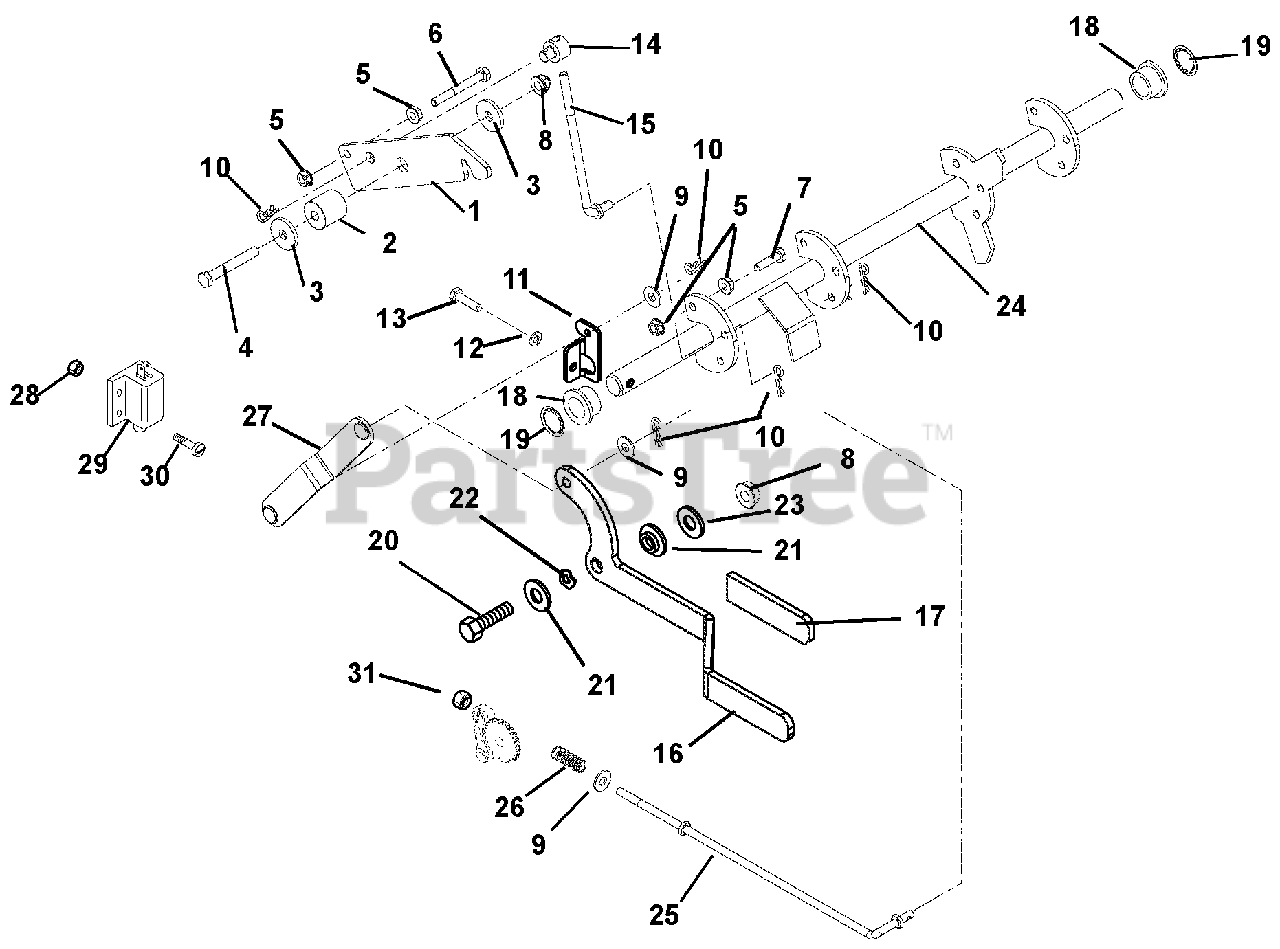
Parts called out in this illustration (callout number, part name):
1	LATCH, NEUTRAL
2	SPCR, FLG .32X.49X.192X1.00
3	WSHR-FL-STL .344X1.125X.135
4	@BLT-HEX .31-18X2.25 GR5 YWZC
5	@NUT-SPNLK-FLG .25-20 YWZC
6	@BLT-HEX .25-20X2.25 GR5 YWZC
7	@BLT-HEX .25-20X1.00 GR5 YWZC
8	@NUT-LK-NYL-FLG .31-18 YWZC
9	@WSHR-FL-STL.312X.734X.065 YWZ
10	PIN-HAIR INT .08X.18X1.18 YWZC
11	CRANK, PARKING BRAKE
12	@WSHR-LK .25X.062 REG YWZC
13	@BLT-HEX .25-20X1.00 GR5 YWZC
14	TRUNNION, BRAKE .31-18 UNC
15	BRAKE LINK
16	HANDLE, PARKING BRAKE
17	GRIP,HANDLE
18	BSHG-FLG .750X1.000X.625X1.250
19	NUT, PUSH -.75" SHAFT
20	@BLT-HEX .31-18X1.75 GR5 YWZC
21	BSHG-FLG .325X.501X.250X1.120
22	WSHR-WAVE .50X.75X.015 .13FRHT
23	WSHR-FL-STL .328X.87X.179 YWZC
24	WNT, BRAKE SHAFT
25	ROD - BRAKE
26	SG-COMP .045X.50X1.187
27	WELDMENT, BRAKE LINK
28	@NUT-LK-NYL 10-24 W/INSRT YWZC
29	SWITCH- DOUBLE POLE N.O./N.O.
30	@SCR-MCH 10-24X.75 HWH YWZC
31	@NUT-LK-NYL .250-20 YWZC
